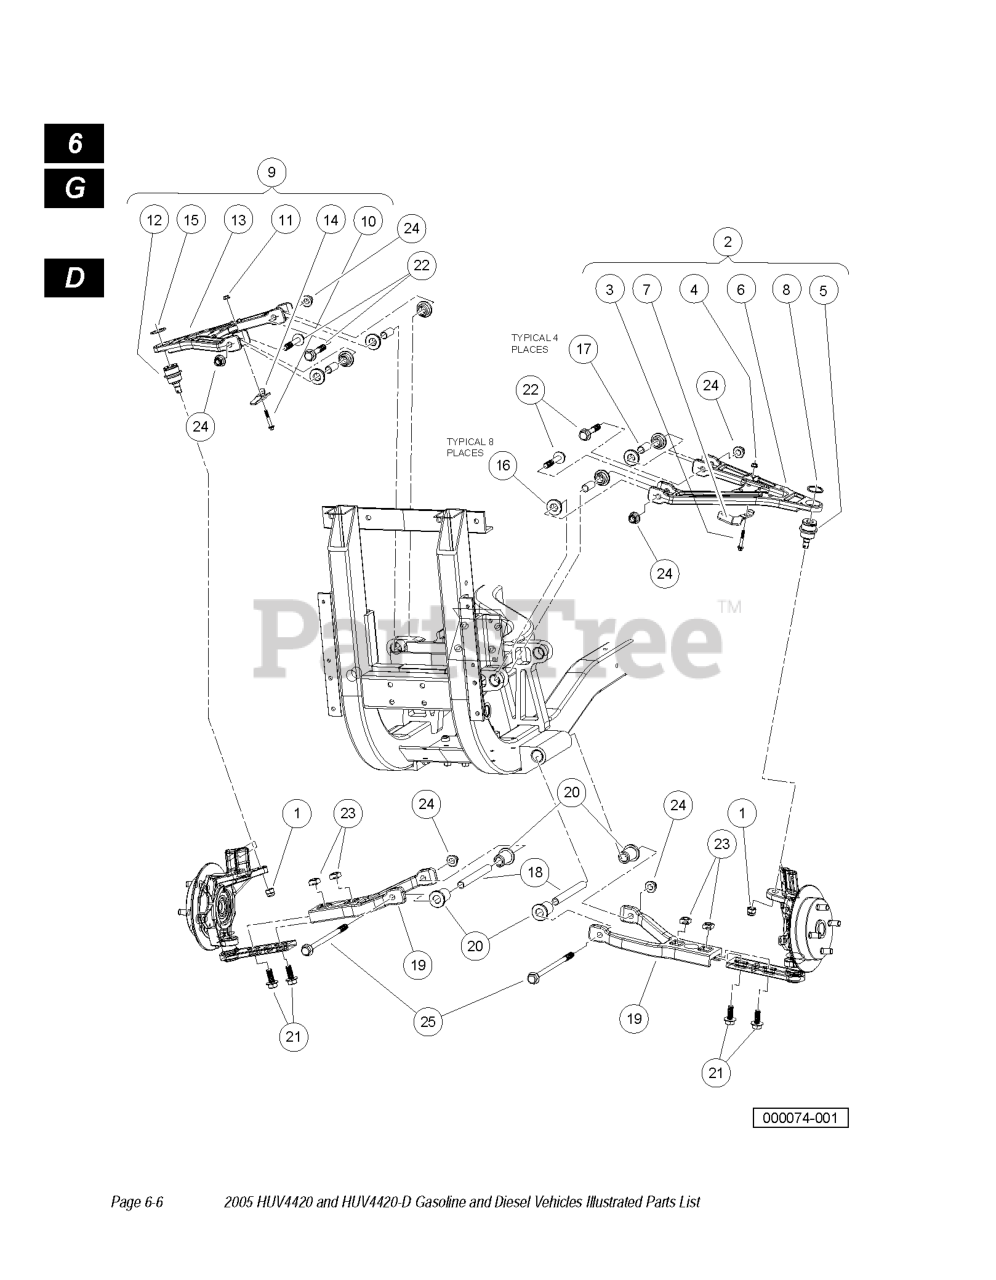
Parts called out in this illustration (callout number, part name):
1	LOCKNUT, M12-1.25 NYLON
2	SUB-ASSEMBLY, A-ARM, UPPER LH
3	BOLT - M6X1.0X40 HEX FLNG HD
4	NUT-M6X1.0 FLNG ALL MTL LOCK
5	BALL JOINT
6	A-ARM, UPPER, LEFT
7	BRACKET, BRAKELINE, LEFT
8	RING, RETAINING, EXT, 1-1/4"
9	SUB-ASSEMBLY,A-ARM, UPPER, RH
10	BOLT - M6X1.0X40 HEX FLNG HD
11	NUT-M6X1.0 FLNG ALL MTL LOCK
12	BALL JOINT
13	A-ARM, UPPER, RIGHT
14	BRACKET, BRAKELINE, RIGHT
15	RING, RETAINING, EXT, 1-1/4"
16	BUSHING, A-ARM
17	SLEEVE, UPPER
18	SLEEVE, LOWER
19	ARM, LOWER
20	BUSHING, LOWER ARM
21	BOLT, FLG, M12X1.75X30
22	BOLT, FLG, M12X1.75X70
23	NUT, SQUARE, M12 X 1.75
24	NUT FLG, M12X1.75, NYLON GR 10
25	BOLT FLG, M12 X 1.75 X 200 10.
